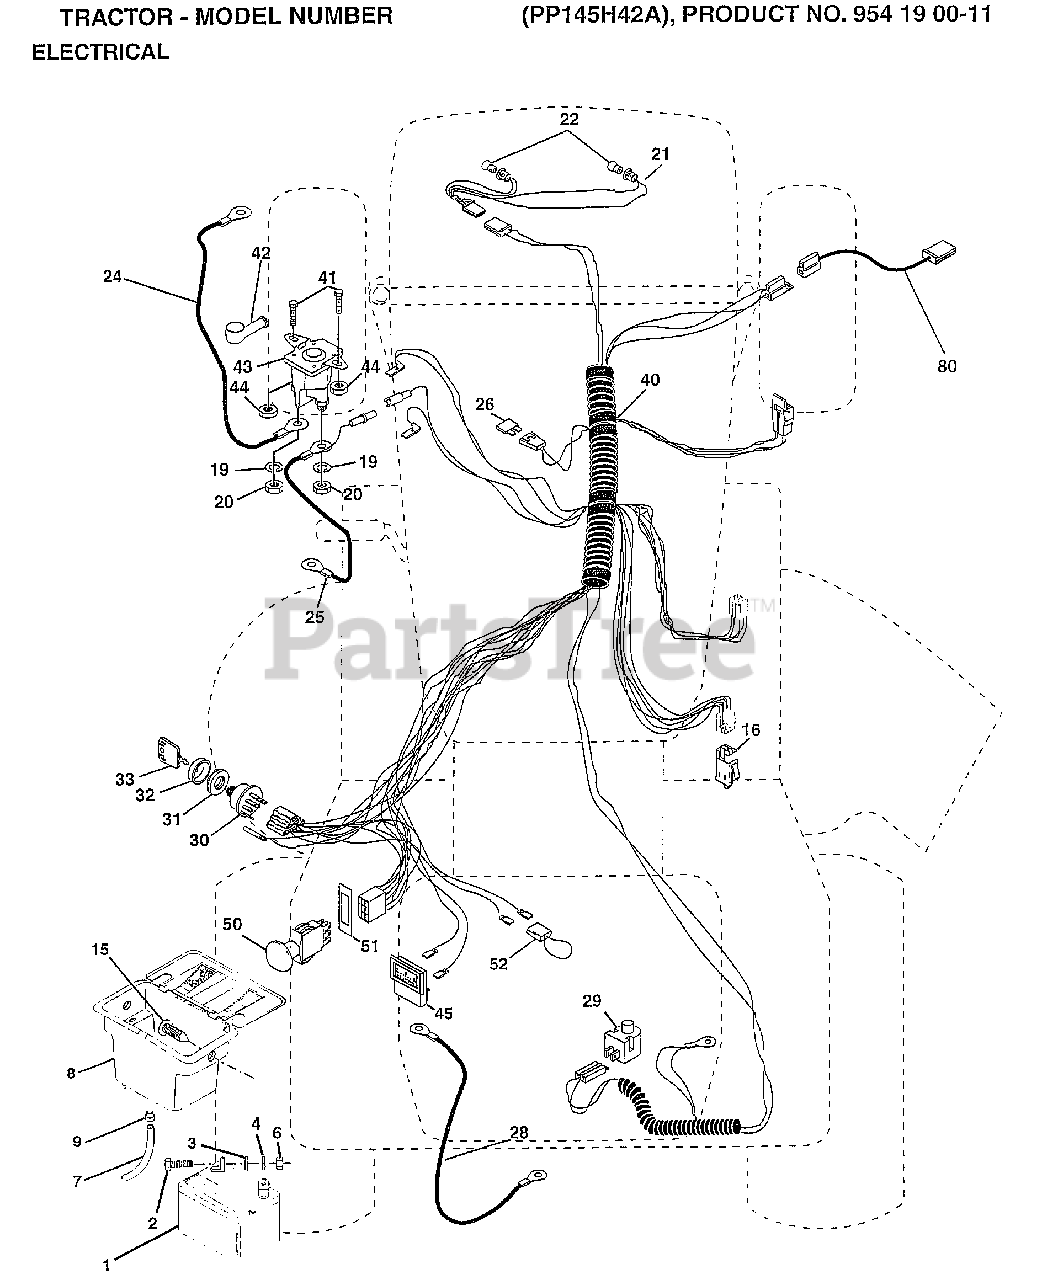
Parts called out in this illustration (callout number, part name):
2	BOLT LT
3	WASHER
4	LOCKWASHER
7	TUBE T
8	"CASE,BATTERY.MECH"
9	HOSE CLAMP T
15	FASTNER.SNAP-IN
16	SWITCH INTERLOCK
20	NUT
21	"HARNESS,LIGHT SOC"
22	HEADLAMP BULB
24	CABLE ASM.
25	CABLE.BTRY.6GA.RD
26	FUSE HYT
28	CABLE T
29	SWITCH SEAT
30	SWITCH IGN 4POS
31	NUT IGNITION
32	COVER KEY SWITCH
33	KEY
40	HARNESS IGNITION
41	BOLT HXHD FIN
44	NUT HXKEP 1/4X20
50	PTO SWITCH.BLK
51	RING RETAIN PTO
52	PROTECTION LOOP
80	HARNESS.CLUT.EVX.
